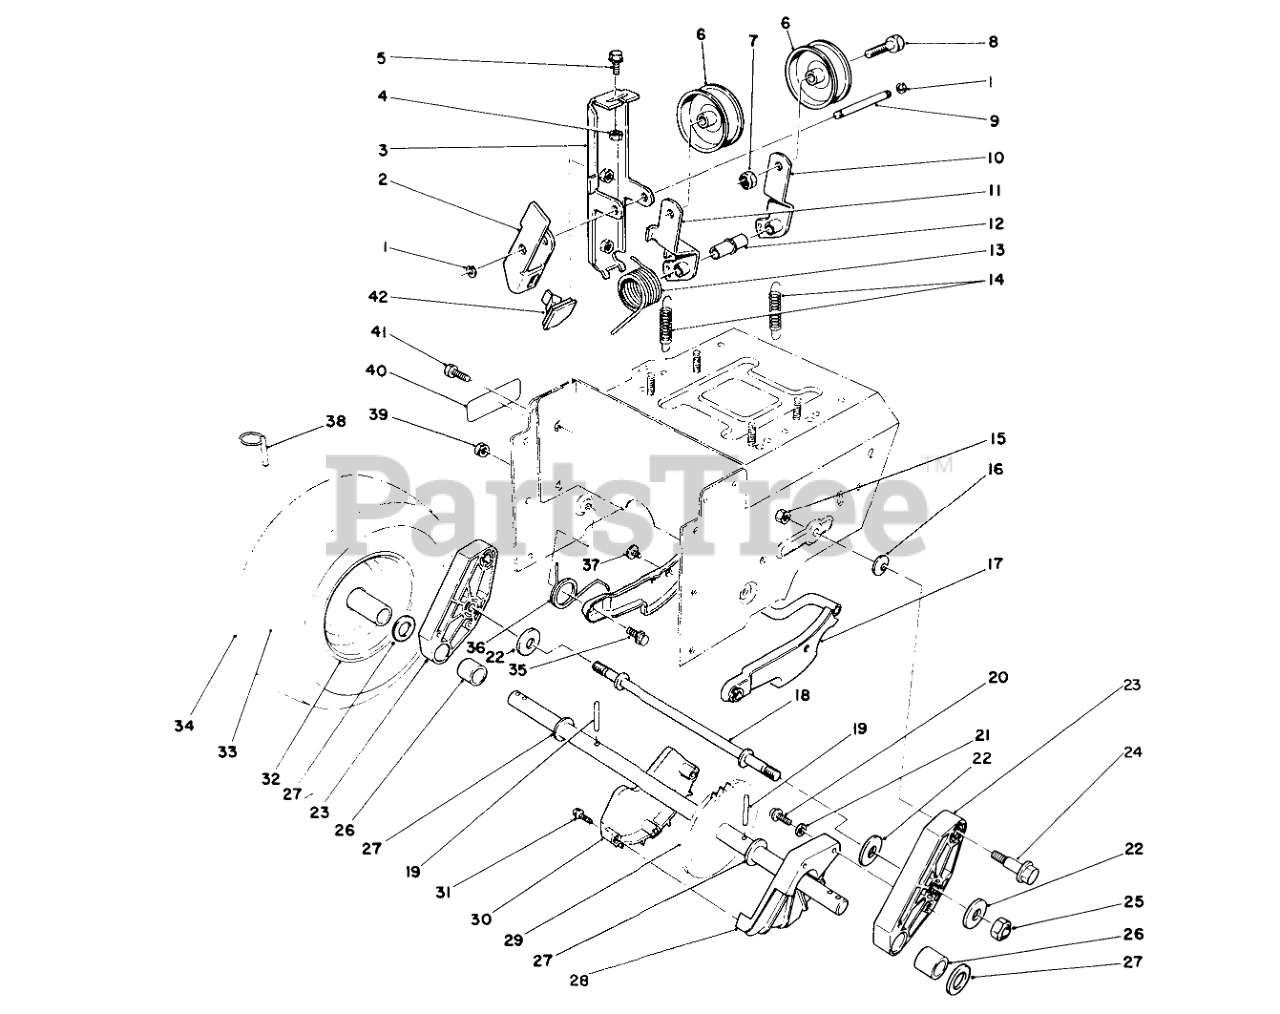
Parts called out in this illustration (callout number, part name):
1	RING-RETAINING
2	ARM-BRAKE
3	IDLER ARM BRACKET ASM
4	NUT-LOCK, NI
5	SCREW-HHF
6	PULLEY-IDLER
7	NUT-LOCK, NI
8	SCREW-HH
9	PIN-IDLER
10	ARM-IDLER, TRACTION
11	ARM-IDLER, IMPELLER
12	BUSHING-IDLER
13	TORSION SPRING
14	SPRING-EXTENSION
15	NUT-LOCK, NI
16	WASHER-SPRING
17	Latch-Arm
18	ROD-LATCH
19	PIN-ROLL, SLOTTED
20	SCREW-HWH
21	WASHER-FLAT
22	WASHER-SUPPORT
23	Pivot Arm Assembly (Incl.Ref. #26)
24	BOLT-SHOULDER
25	NUT-LOCK, NI
26	BUSHING-AXLE
27	WASHER-THRUST
28	GUARD-CHAIN, LH
30	GUARD-CHAIN, RH
31	SCREW-PPH
32	RIM-WHEEL
33	INNER TUBE
35	SCREW-SHOULDER
36	SPRING-LATCH, TORSION
37	FASTENER-PANEL
38	PIN-LYNCH
39	NUT-LOCK, NI
40	Decal-Warning
41	SCREW-HHF
42	PAD-BRAKE
